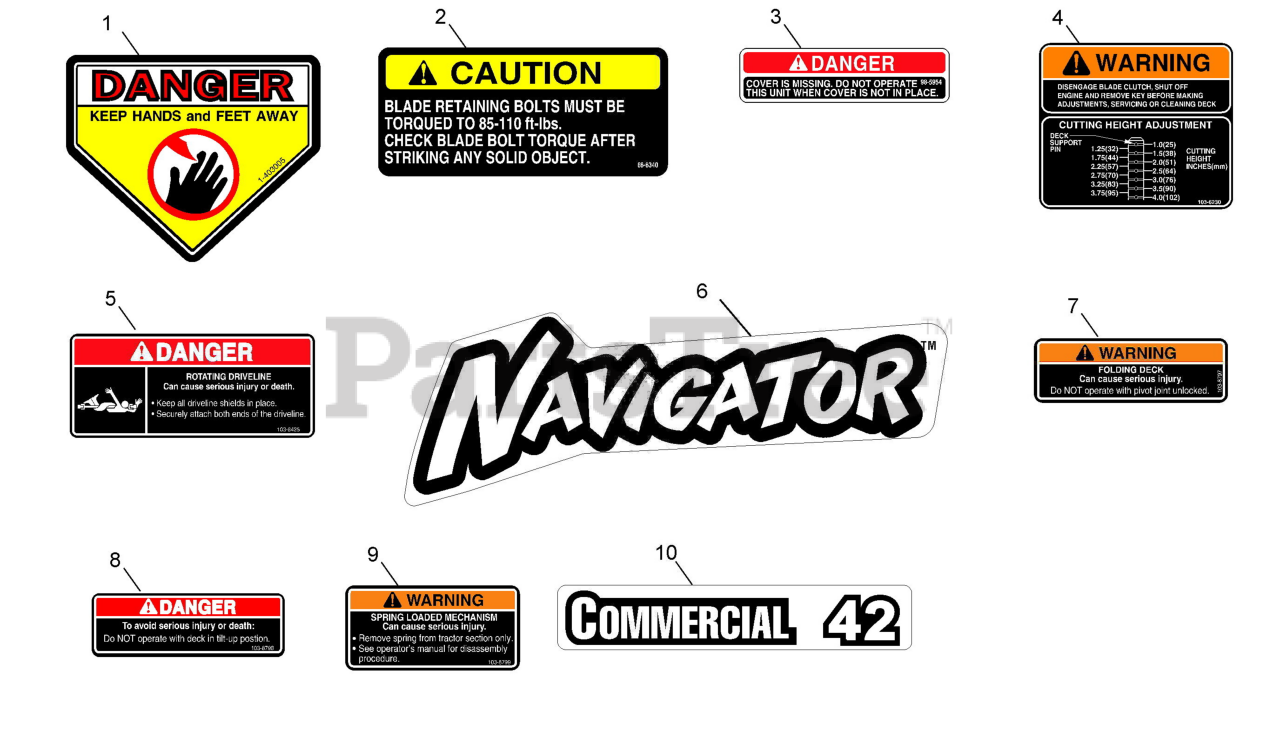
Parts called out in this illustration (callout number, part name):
1	DECAL-DANGER
2	DECAL-TORQUE
3	DECAL-COVER, MISSING
5	DECAL-DRIVELINE
6	DECAL,NAVIGATOR MODEL
7	DECAL-FOLDING DECK
8	DECAL-DANGER
9	DECAL-SPRING
10	DECAL,COMMERCIAL 42
